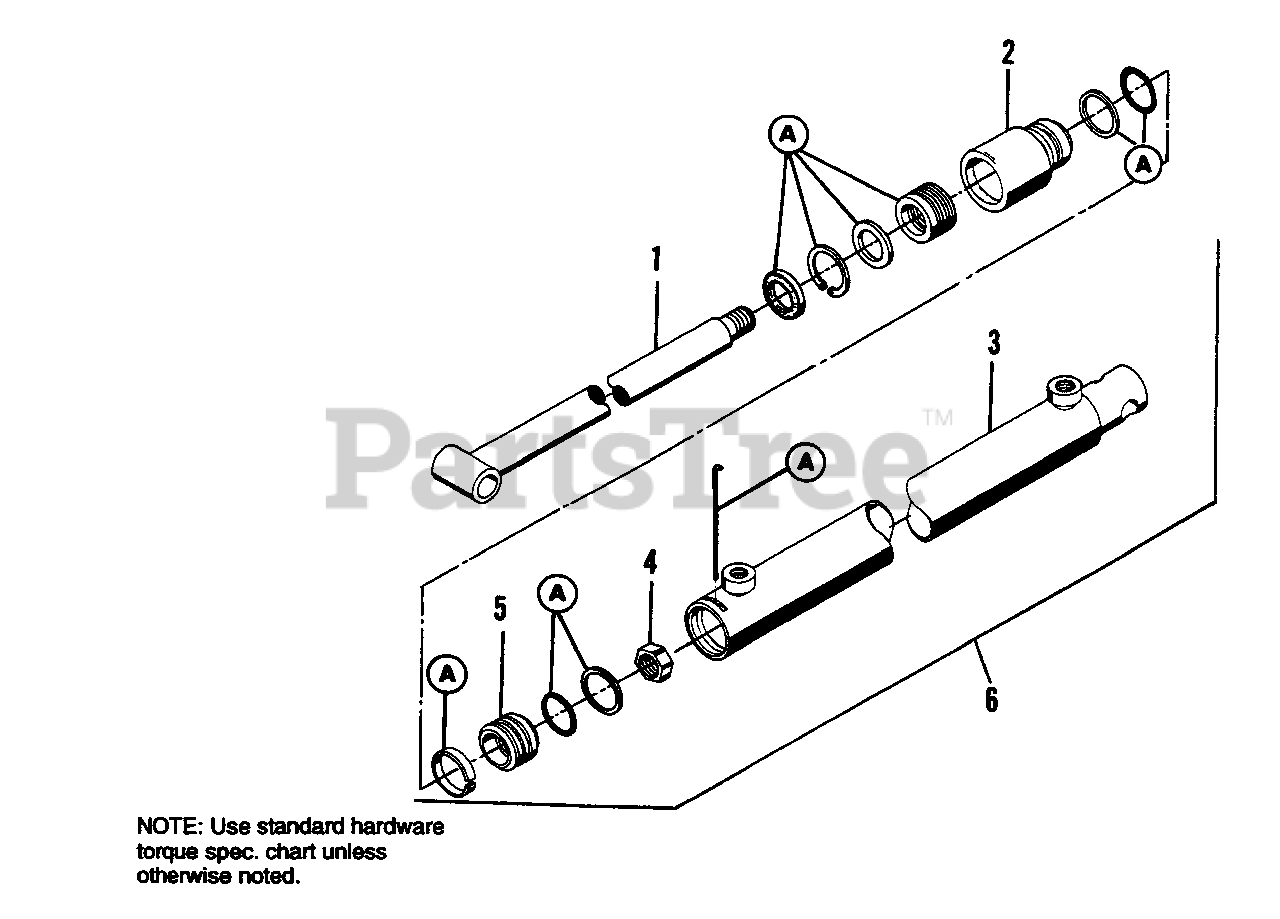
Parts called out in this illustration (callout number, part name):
1	SHAFT, Cylinder
2	HEAD, Cylinder
3	TUBE, Cylinder
4	LOCKNUT, Jam, 3/4-10
5	PISTON, Cylinder
6	COMPLETE CYL. ASST. LIFT
A	SEAL REPAIR KIT
